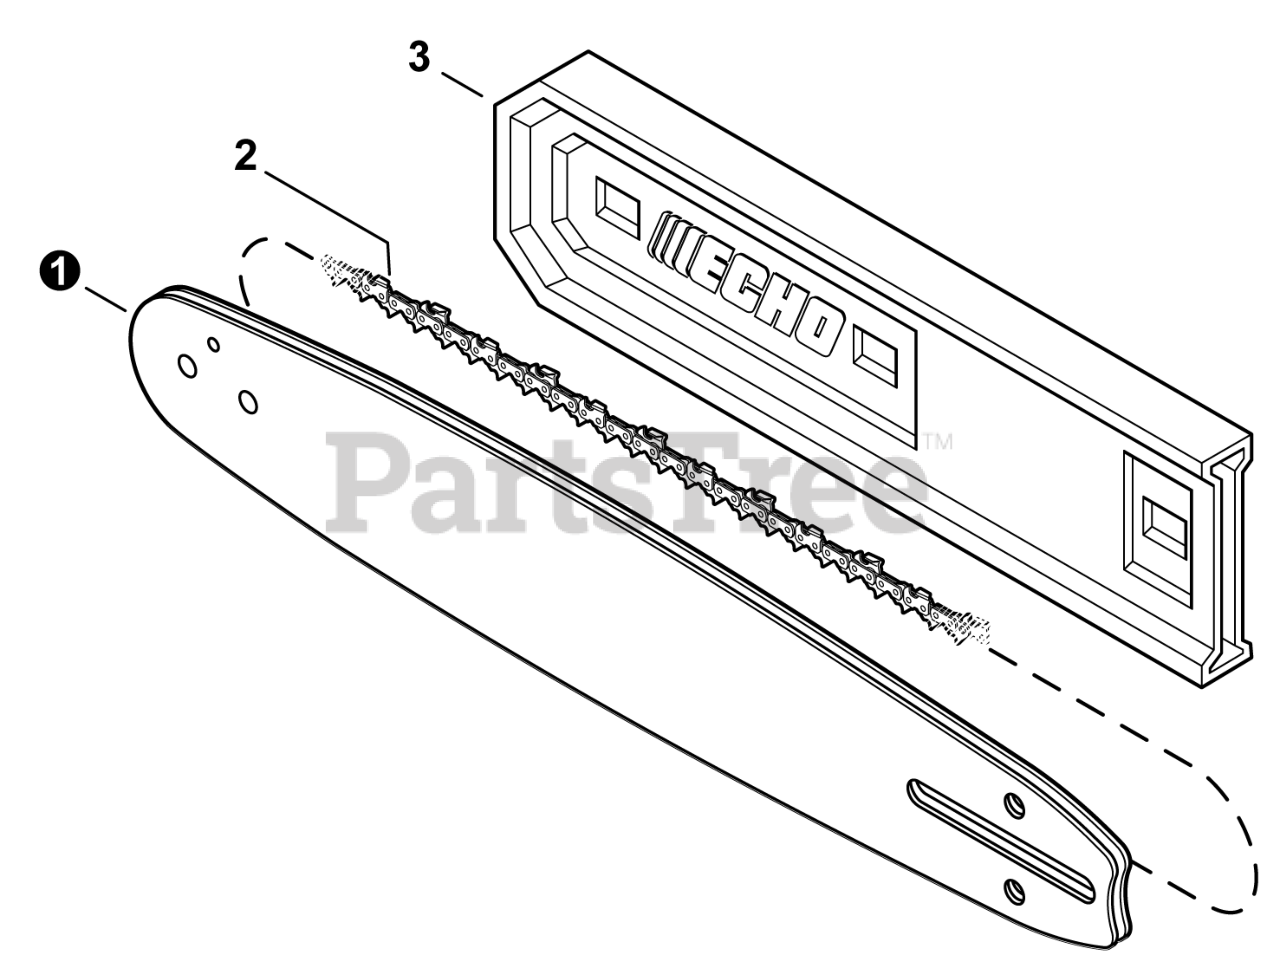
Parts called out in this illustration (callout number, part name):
1	GUIDE BAR, 12"
2	SAW CHAIN 12"
3	SCABBARD 12"
